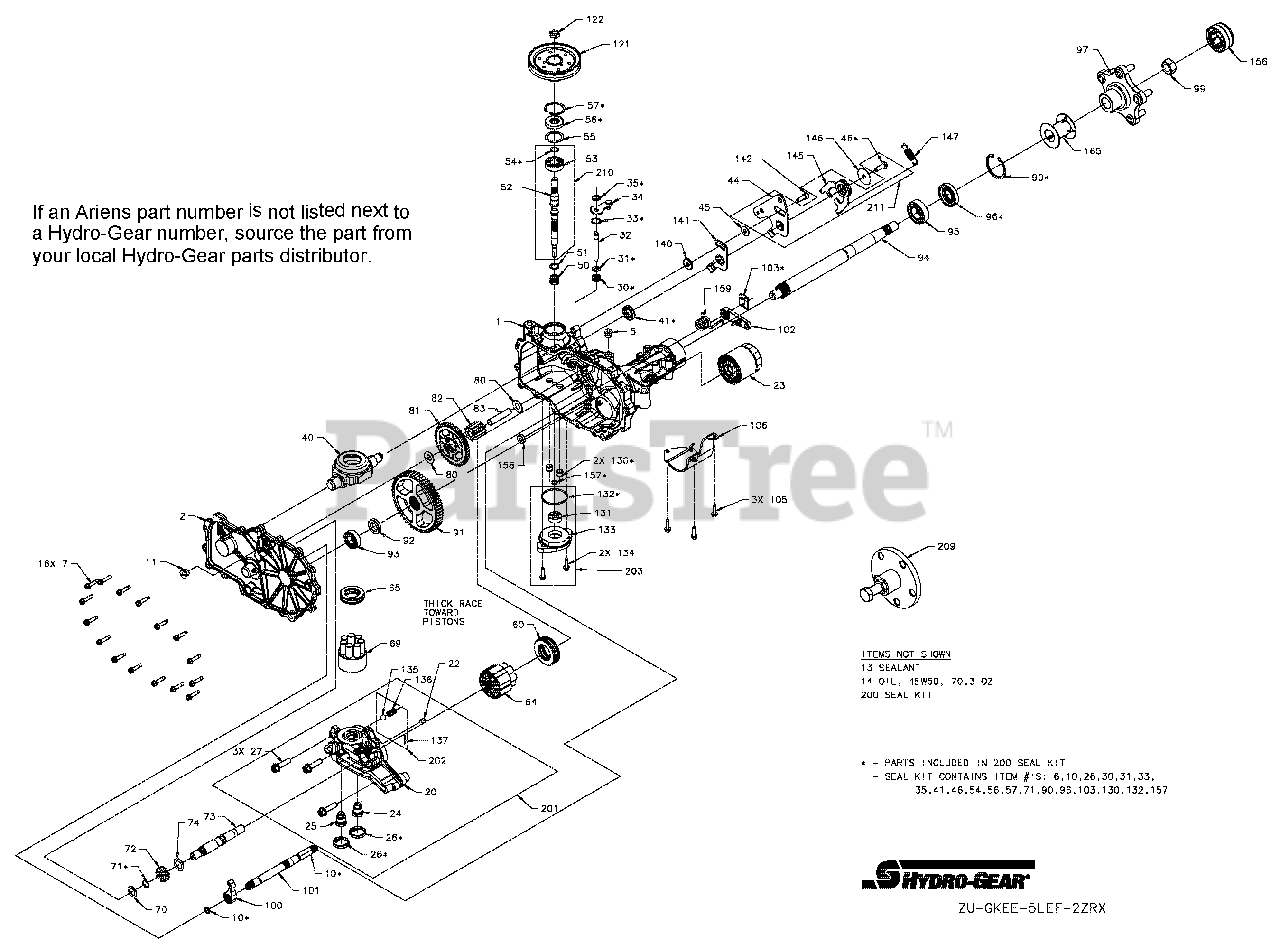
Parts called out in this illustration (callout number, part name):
7	HFHCS 1/4-20 x 1.125"
13	SEALANT
22	PLATE, BYPASS
23	FILTER, OIL
26	SEAL, PLUG 1.250 x .250
30	SEAL, LIP .375 x .75 x .25
31	RING, RET .375 EXTRNL
33	RING, RET .750 INTRNL
34	ARM, BYPASS
35	RING, RTNG .375 EXT
40	TRUNNION, SWASHPLATE
41	SEAL, LIP 12 x 32 x 7
45	WASHER .34 x .88 x .06
46	TWHCS 5/16-24 x 1.00 (PATCH)
50	SPRING, BLOCK
51	WASHER-FLAT .59 x .79 x .04
55	WASHER 1.23 x 1.56 x .04
56	SEAL, LIP 17 x 40 x 7
57	RING, RETAINING
60	BEARING, THRUST
64	ASS'Y, CYLINDER BLOCK, 16cc
65	BRG, THRUST PLASTIC CAGE
69	ASS'Y, BLOCK 7 PISTON
70	WASHER .63 x 1.0 x .05
71	RING, RETAINING_.625
74	WASHER .72 x 1.16 x .04
80	WASHER .5 x 1.0 x .03
83	JACK SHAFT (PIN)
90	RING, RET 2.06 INT
95	BRG, BALL 25.4 x 52 x 15
96	SEAL, LIP 1.000 x 2.049 x .375
97	KIT, HUB, 5 BOLT
99	NUT, HEX LOCK 3/4-16
102	KIT, HANDLE, ACTUATING
103	CLIP, RETAINING
121	PULLEY, 4.5 x 1.625
122	NUT,HEX JAM 1/2-20 W/ PATCH
131	GEROTOR ASSEMBLY (1.9 cc/rev)
132	O-RING, -137, 0.103 x 2.050
140	SPACER .320 x 1.005 x .179
141	ARM, NEUTRAL RIGHT
142	SHCS 5/16-24 x 1 PATCH
146	WASHER, .343 x 1.500 x .062
147	SPRING, EXTNSN RTN-34LBS
157	SEAL, LIP 8 x 12 x 3 VC
158	MAGNET, RING
159	SPRING, TORSION CCW
200	KIT, SEAL
201	KIT, CENTER SECTION, RH, CHRG
203	KIT, CHARGE PUMP
